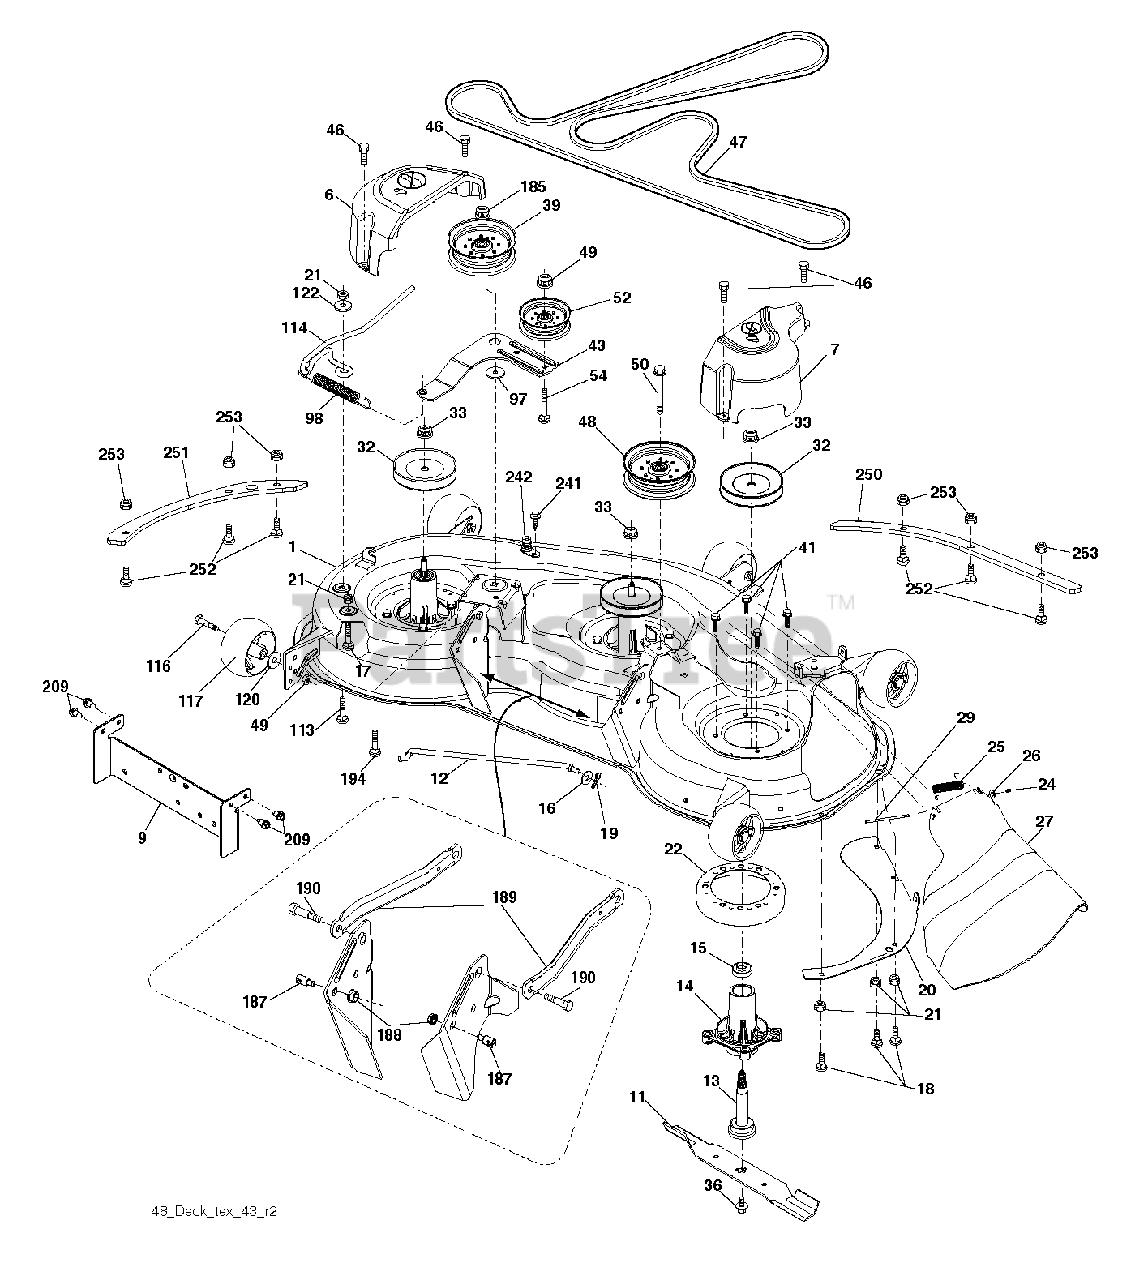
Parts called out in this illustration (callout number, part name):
1	DECK SVC 48"TEX.
6	COVER.MANDREL.LH.48"
7	Mandrel Cover, RH 48"
9	TORQUE STRAP PNT BLACK
11	48" HI-LIFT BLADE
12	ROD.ANTI.SWAY.48/54"K4
13	Mandrel Assembly, Greaseable
14	HOUSING.MANDREL.4PT.
15	Extended Mandrel Bearing, Top
16	WASHER
17	BOLT
18	BOLT
19	PIN.COTTER.5/16.BOW TI
20	BAFFLE, VORTEX MWR
21	LOCKNUT
22	STRIPPER.MANDREL.ROUND.BLACK
24	CAP-SLEEVE LT
25	SPRING, TORSION
26	NUT PUSH M
29	ROD.HINGE
32	PULLEY MANDREL
33	NUT.FLANGE.LOCK.TOP
36	Screw, 7/16 X 20 X 1"
39	PULLEY.IDLER.4.50/HUB SPECIAL
41	Hex Washer Head Bolt, .313-18 X 1.19
43	ARM.IDLER
46	SCREW.1/4-20X5/8
47	BELT.DRIVE.DECK
48	PULLEY.IDLER.2006
49	NUT LOCK FLG 3/8-16 UNC
50	SCREW TT 3/8-16X2-1/4 UNC
52	PULLEY.IDLER.48"PRIMARY
54	BOLT.3/8-16X1.50
98	SPRING, DECK DRIVE
113	BOLT CRT
114	ROD.TENSION.RELIEF.TEX (2 2)
116	BOLT.SHOULDER.3/8-16X3-5/8.
117	WHEEL. GUAGE RALLY
122	BUSHING.RELIEF.TENSION
185	NUT.LOCK.FLANGE.7/16
187	STUD.FASTNER.W/ANTI-ROTATE
188	NUT LOCK HEX FLANGE 5/16-18
189	ARM.SUSPENSION.MOWER
190	BOLT.SHOULDER
194	BOLT.HEX.WASHER.HEAD.7/16-24X
209	SCREW
241	SCREW.TT.#10-32X.5.3/8.FLANGE
242	PORT.WASHOUT
250	Front Reinforcement Plate, 48" Bolt-on
251	Side Reinforcement Plate, 48" Bolt-on
252	RHSNB, 1/4-20 X 1, GR5
253	NUT T
